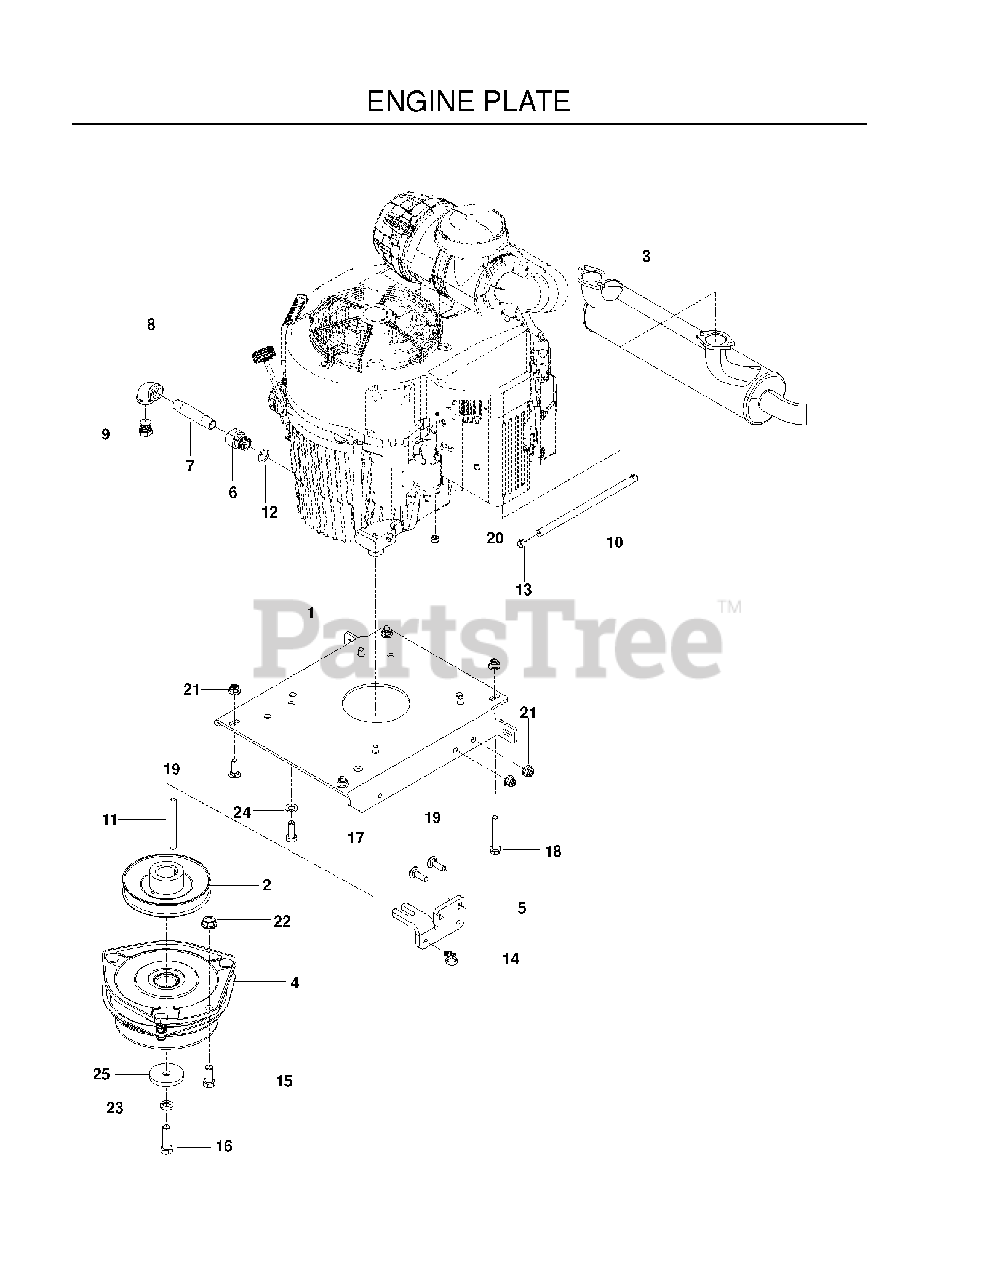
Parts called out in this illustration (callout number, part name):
1	PLATE.ENGINE.BLACK
2	PULLEY, ENGINE
3	MUFFLER, 29HP KAW FX751V-850V
4	CLUTCH, GT3.5
5	STOP, CLUTCH, OGURA
6	ADAPTER, OIL DRAIN
7	PIPE NIPPLE 3/8 X 3
8	90 DEG.ELBOW 3/8NPT
9	PLUG, DRAIN 3/8 NPTF
10	GAS LINE 10"
11	KEY, 1/4 SQ X 3.5
13	HOSE CLAMP
14	TIE WRAP, 8-3/8", W/CLIP
15	HCS 7/16-14 X 1 GR 5 ZD
16	HCS 7/16F X 1 1/2
17	HCS 3/8-16X1.GRD.5.ZD
18	HHFS 5/16-18 X 2.25 GD 5
19	RHSNB 5/16C X 1
20	NUT M8-1.25 TOP NYL GR10 ZD
21	5/16-18 NYLOC FLANGE NUT
22	NUT 7/16C WHIZ
23	WASHER 7/16 LOCK
24	WASHER, 3/8 DISC SPRING SPEC
25	BLADE WASHER
